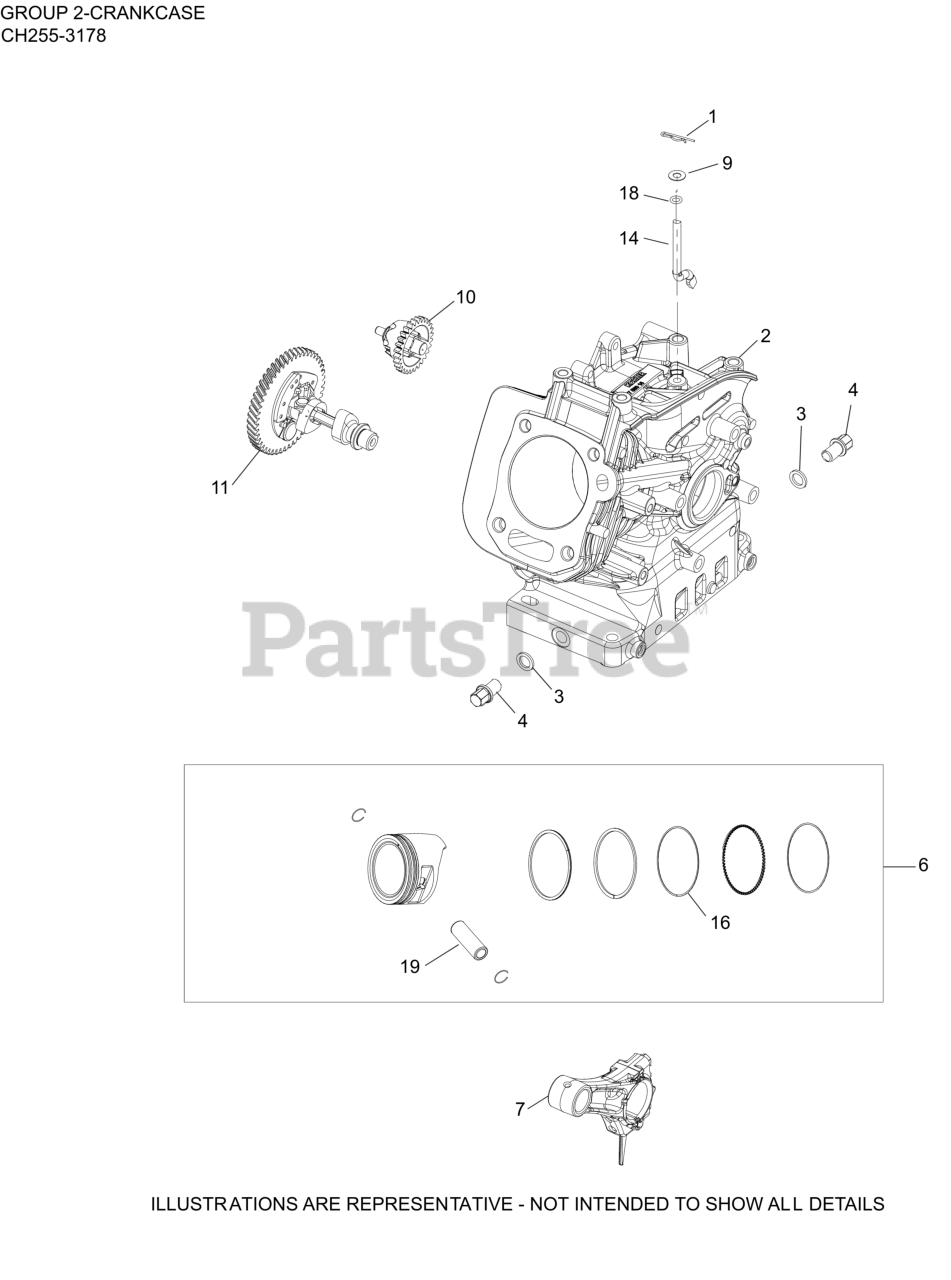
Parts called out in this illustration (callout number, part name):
1	CLIP, GOVERNOR SHAFT
2	CRANKCASE
3	WASHER, DRAIN PLUG
4	KIT, DRAIN PLUG
6	KIT, PISTON (STD)
7	ROD, CONNECTING ASSEMBLY
9	WASHER, FLAT (DIA 13mm O.D.)
10	GOVERNOR ASSEMBLY
14	SHAFT, GOVERNOR CROSS
19	PIN, PISTON
